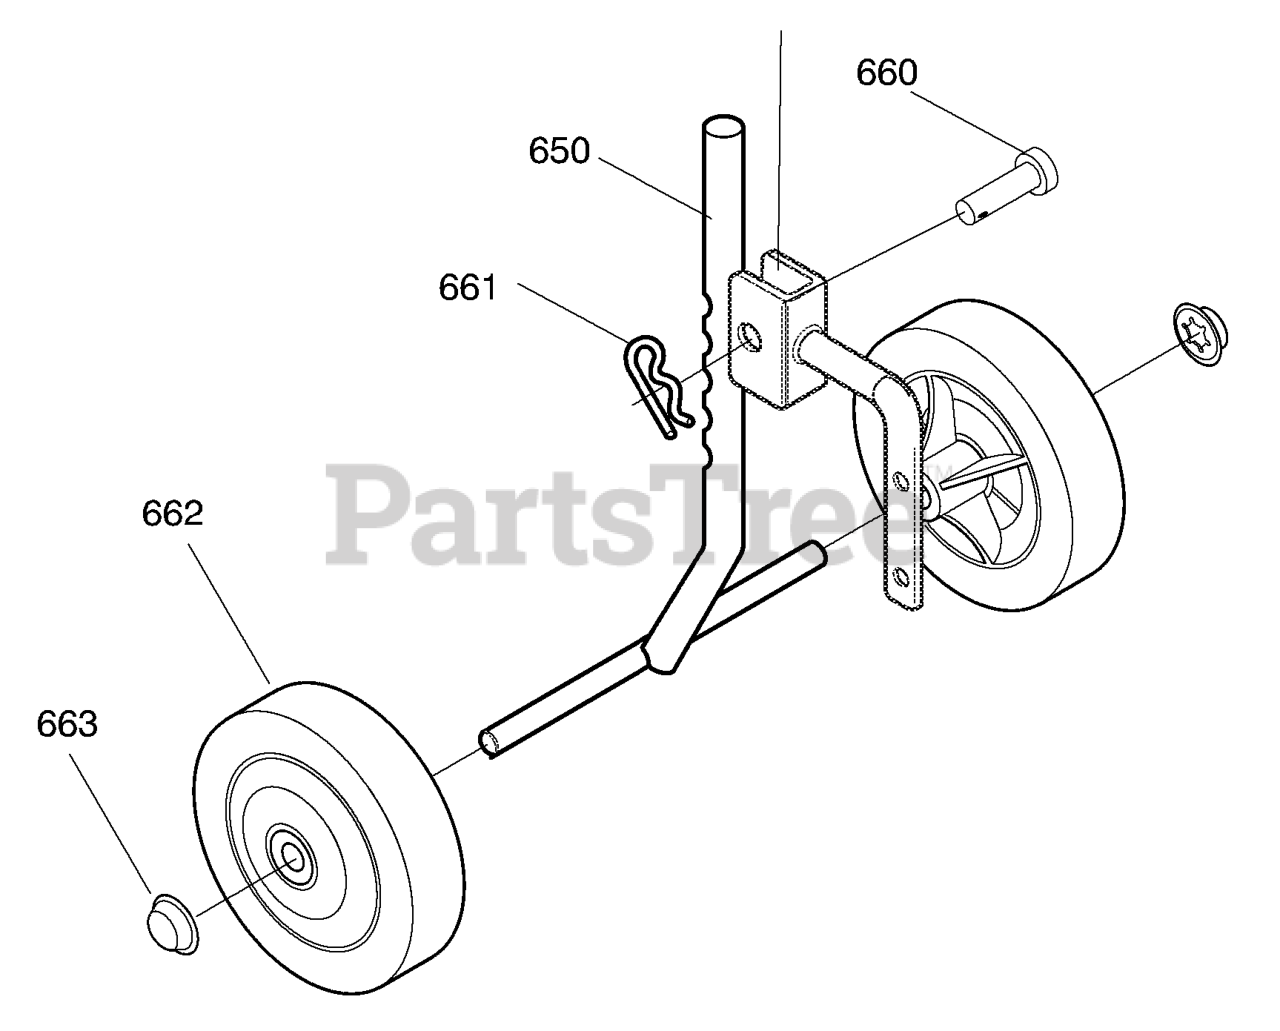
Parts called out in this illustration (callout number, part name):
650	Wheel Support Assy.
660	Clevis Pin
661	Hair Pin
662	Tire & Rim
663	Push On Nut
